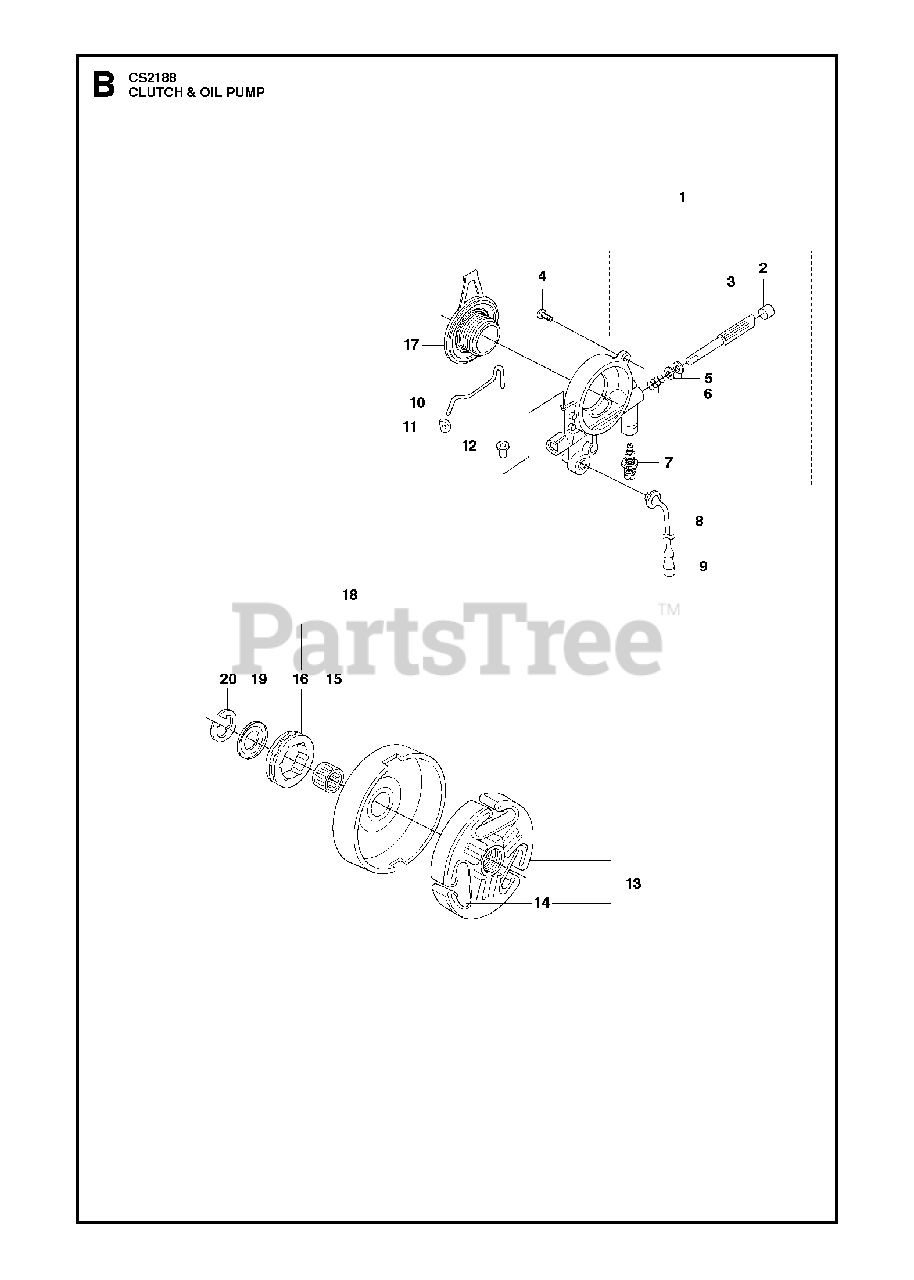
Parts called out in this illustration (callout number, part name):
2	PLUG
3	PUMP PISTON
4	SCREW MC6S 5X16
5	WASHER 6.1X9
6	SPRING
7	INSERT OIL PUMP
9	OIL SCREEN
14	CLUTCH SPRING
15	CLUTCH DRUM BEARING
16	68210 RIMSPROCKET
16	22273 SPROCKET
18	CLUTCH ASSY
20	RETAINING RING
